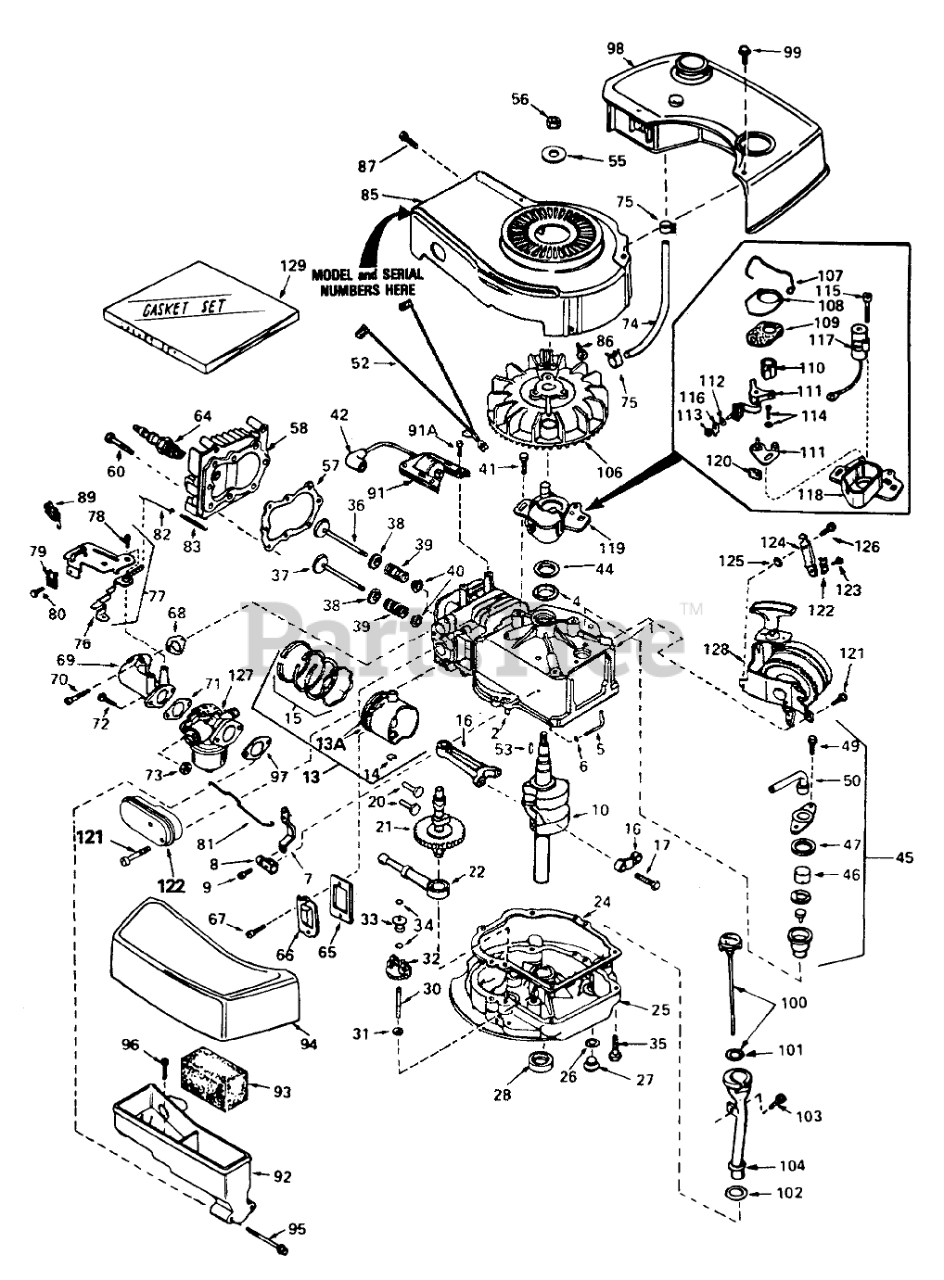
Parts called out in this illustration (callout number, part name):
1	Cylinder Assy. (Incl. Nos. 2, 4 & 121)
2	Pin-Dowel
4	Seal-Oil
5	Rod, Governor (Incl. No. 6)
6	Washer-Flat
7	Governor Lever
8	Clamp-Lever, Governor
9	Screw
10	Crankshaft
13	Piston, Pin & Ring Assy. (Incl. Nos. 13A, 14 & 15)(Std.)
13	Piston, Pin & Ring Assy. (Incl. Nos. 13A, 14 & 15)(.010 oversize)
13	Piston, Pin & Ring Assy. (Incl. Nos. 13A, 14 & 15)(.020 oversize)
13A	Piston & Pin Assy. (Incl. No. 14)(Std.)
13A	Piston & Pin Assy. (Incl. No. 14)(.010 oversize)
13A	Piston & Pin Assy. (Incl. No. 14)(.020 oversize)
14	Ring-Retaining, Piston Pin
15	Ring Set Piston (Std.)
15	Ring Set Piston (.010 Oversize)
15	Ring Set Piston (.020 Oversize)
16	Rod Assy., Connecting (Incl. No. 17)
17	Bolt-Rod, Connecting
20	Lifter, Valve
21	Camshaft(Mech.Comp. Release)
22	Oil Pump ASM
24	Gasket, Mounting
25	Flange Assy., Mounting (Incl. Nos. 26 thru 30)
26	Gasket-Oil Drain
27	Plug Oil Drain
28	Seal Oil
30	Shaft-Governor
31	Washer-Flat
32	Gear Assy., Governor (Incl. No. 31)
33	Spool-Governor
34	Ring-Retaining
35	Screw (1/4-20 x 1-1/4)
36	Valve, Intake (Stcl.)(Incl. No. 40)
36	Valve, Intake (1/32" oversize)(Incl. No. 40)
37	Valve, Exhaust (Std.)(Incl. No. 40)
37	Valve, Exhaust (1/32" oversize)(Incl. No. 40)
38	Cap-Upper Valve Spring
39	Spring-Valve
40	Cap-Valve, Spring
42	Cover-Spark Plug
44	Gasket Stator
45	Breather Assy. (Incl. Nos. 46 thru 51)
46	Element-Breather
47	Gasket-Breather
49	Screw (10-24 x 9/16)
50	Tube, Breaker
52	Wire Ground
53	682488 LB GRASS HI-
55	Washer-Belleville
56	Nut-Flywheel
57	63573 GIL 42 SNWTHW
58	Head-Cylinder
60	Screw (5/16-18x1-1/2)
64	Plug, Spark (J17LM or equiv.)
64	Plug, Spark (Champion RCJ-8)
65	Gasket-Breather
66	Cover-Valve
68	Gasket-Intake
69	Pipe, Intake (Incl. No. 68)
70	Screw (1/4-20 x 1)
71	Gasket-Carburetor
72	Screw (1/4-28 x 7/8)
73	Nut and Lock Washer (1/4-28)
74	Line-Fuel
75	Clamp-Line, Fuel
76	Lever Control
77	Control Assy., Speed (Incl. Nos, 76, 78 & 89)
78	Screw, Hex Washer Hd Shoulder Self-Tap
79	Conduit
80	Screw (10-32 x 3/8)
81	Link-Throttle
82	Link Governor Spring
83	Spring Governor
85	Housing Blower
86	Screw
87	Screw (10-24 x 9/16)
89	Terminal
91	Lamination & Coil Assy. (Incl. No. 42)
91A	Screw
92	Body Air Cleaner
93	Filer, Air
94	Cove, Air Cleaner
95	Screw Fil Hd.
96	Screw, Hex Hd.
97	Gasket-Air Cleaner
98	Tank, Fuel
99	Screw (10-32 x 35/64)
100	Dipstick, Oil (Incl. No. 101)(Twist Lock)
103	Screw (10-32 x 1/2)
104	Tube-Oil Fill
106	FIywheel
107	Spring Breaker Box
108	Cover-Dust
109	Gasket-Dust Cover
110	Cam-Breaker
111	Breaker Assy.
114	Breaker Screw
115	Condenser Screw
116	Terminal, Ground
117	Condenser
118	Stator Plate
119	Stator Plate Assy. (incl. Nos. 107, 111 thru 118 & 120)
120	Felt,Cam Wiper
121	Screw (1/4-20 x 1/2)
122	Muffler
127	Carburetor (Incl. No. 71)
128	Starter, Side Mount
129	Gasket Set
